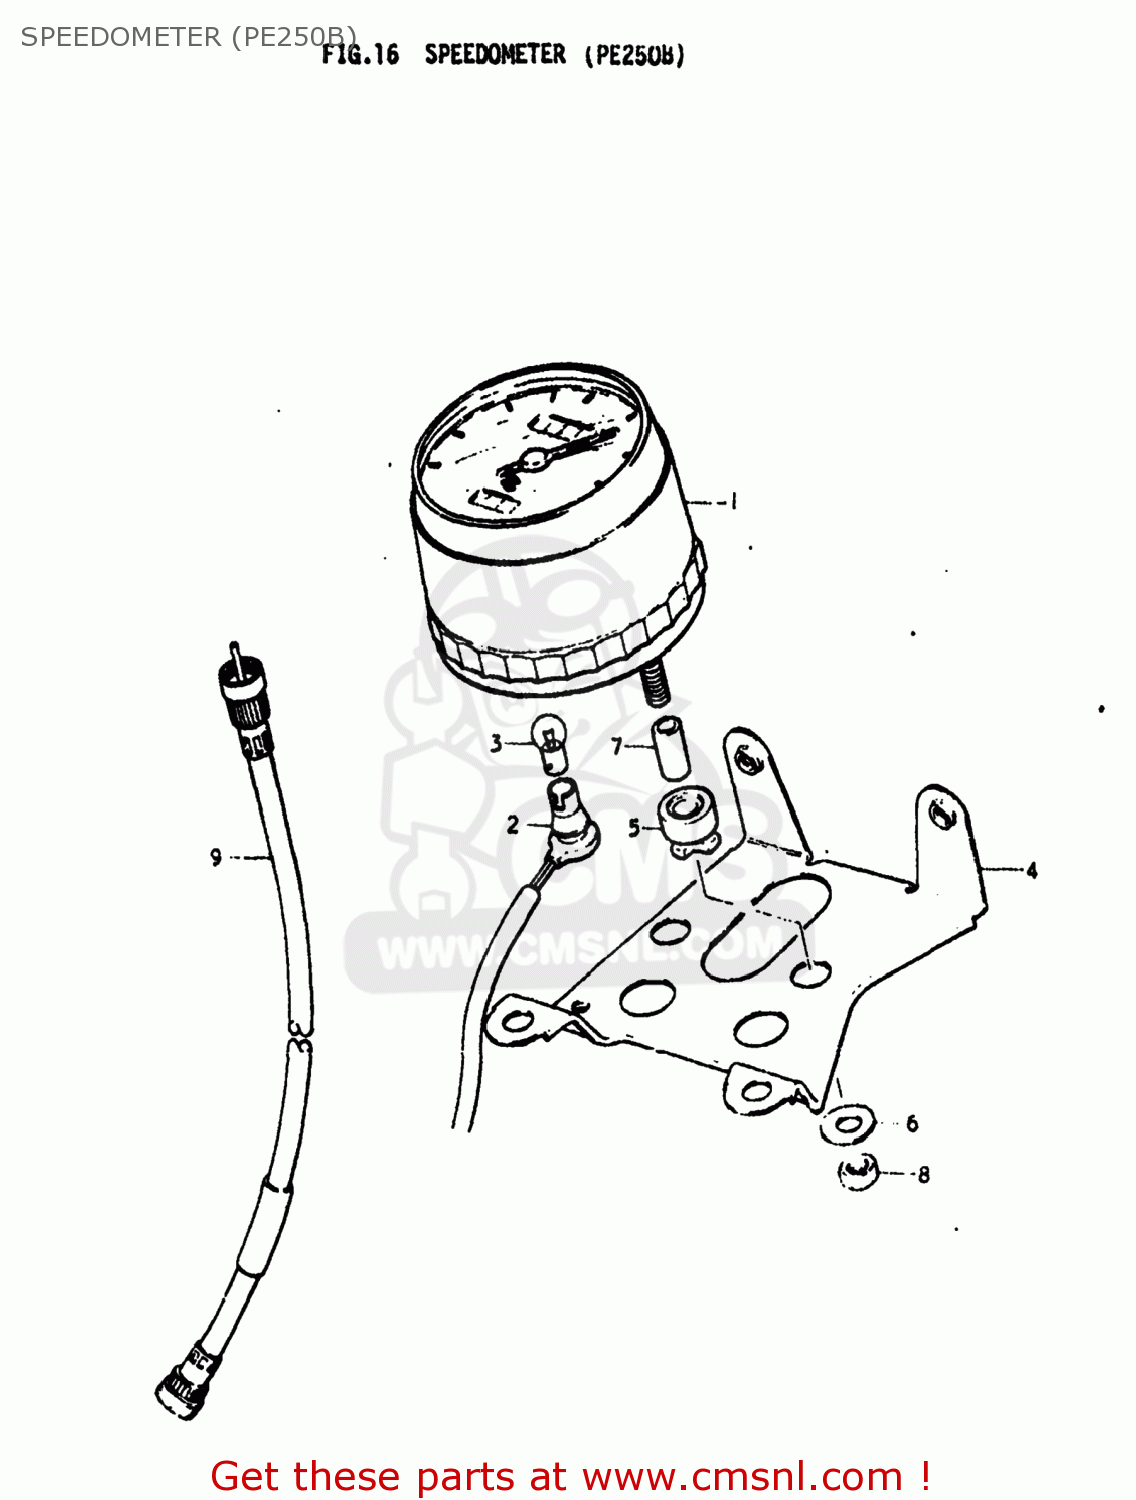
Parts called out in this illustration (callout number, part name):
1	SPEEDOMETER ASSEMBLY
2	SOCKET,METER
3	BULB(6V/3W)
4	BRACKET,METER
5	CUSHION,METER NO.1
6	WASHER
7	SPACER,METER
8	NUT
9	CABLE ASSEMBLY,SPEEDOMETER
